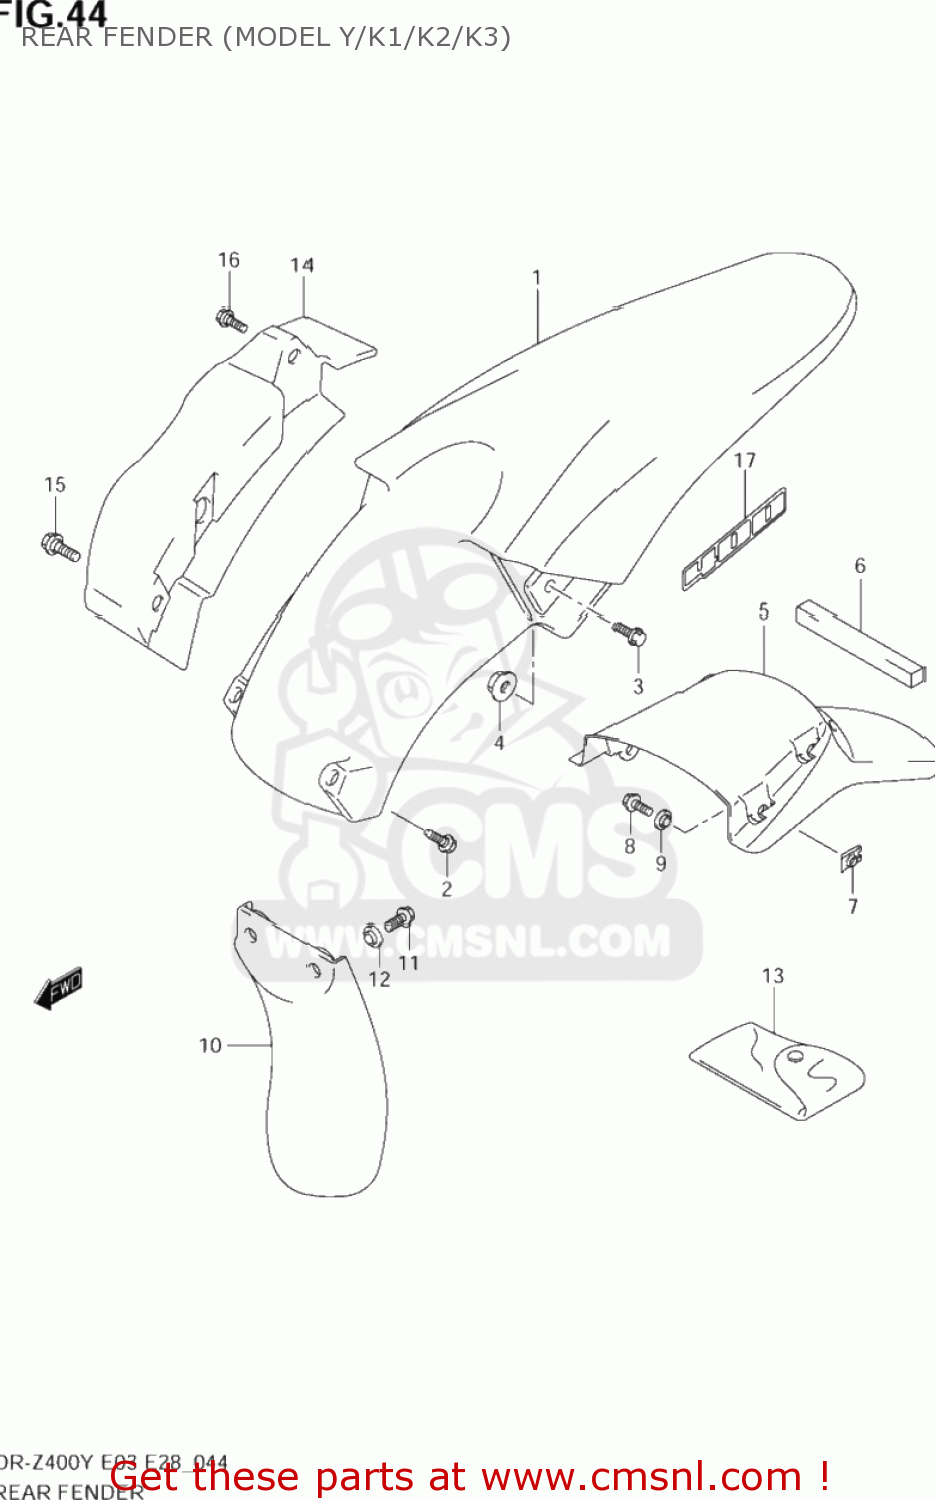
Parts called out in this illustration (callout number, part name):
1	FENDER,RR
2	BOLT(6X16)
3	BOLT(6X18)
4	NUT
5	EXTENSION,RR FENDER
6	CUSHION,RR EXTENSION
7	NUT
8	BOLT
9	WASHER (5X14X1)
10	MUDGUARD,RR FENDER FR
11	BOLT
12	WASHER
13	SPANNER,OPEN
14	MUDGUARD,RR FENDER,R
15	BOLT(6X18)
16	BOLT
17	EMBLEM,RR FENDER
